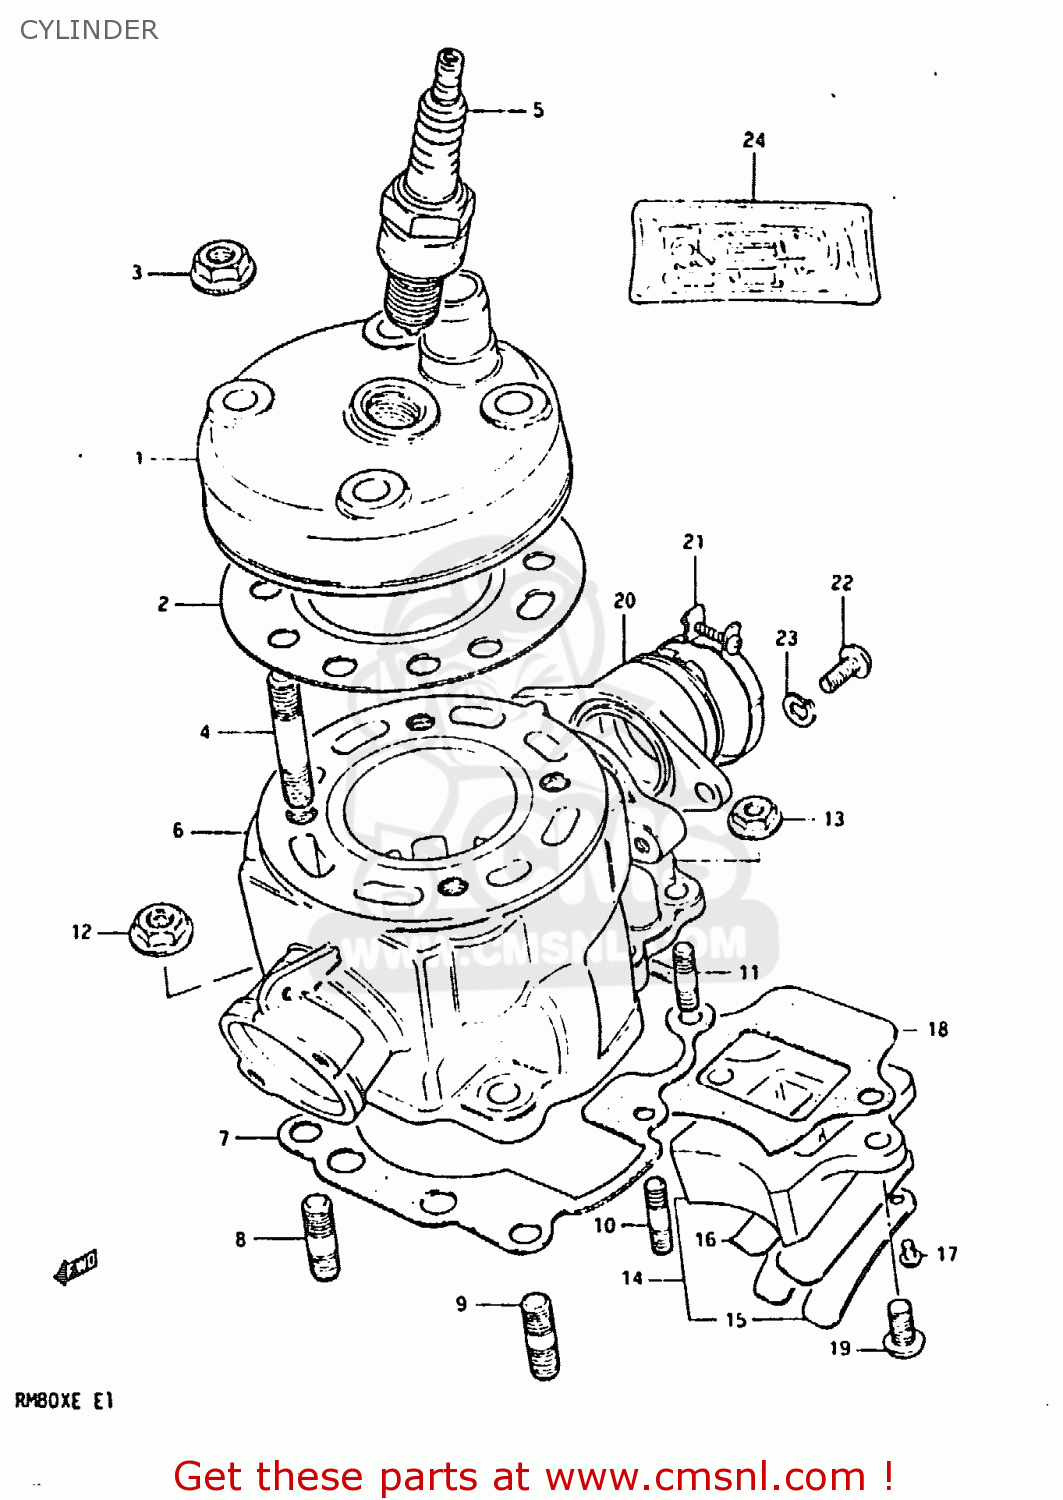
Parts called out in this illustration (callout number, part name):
1	HEAD,CYLINDER
2	GASKET,CYLINDER HEAD
3	NUT 8MM
4	BOLT,STUD
5	SPARK PLUG
6	CYLINDER
7	GASKET,CYLINDER (MCA)
8	BOLT,STUD(8X20)
9	STUD BOLT
10	STUD BOLT L:20
11	STUD 6X16
12	NUT 8MM
13	NUT
14	VALVE ASSY,REED
15	STOPPER,REED VALVE
16	VALVE,REED
17	SCREW,REED VALVE
18	GASKET,REED VALVE (MCA)
19	SCREW
20	PIPE,INTAKE
21	CLAMP
22	BOLT
23	LOCK WASHER
24	GASKET SET (MCA)
